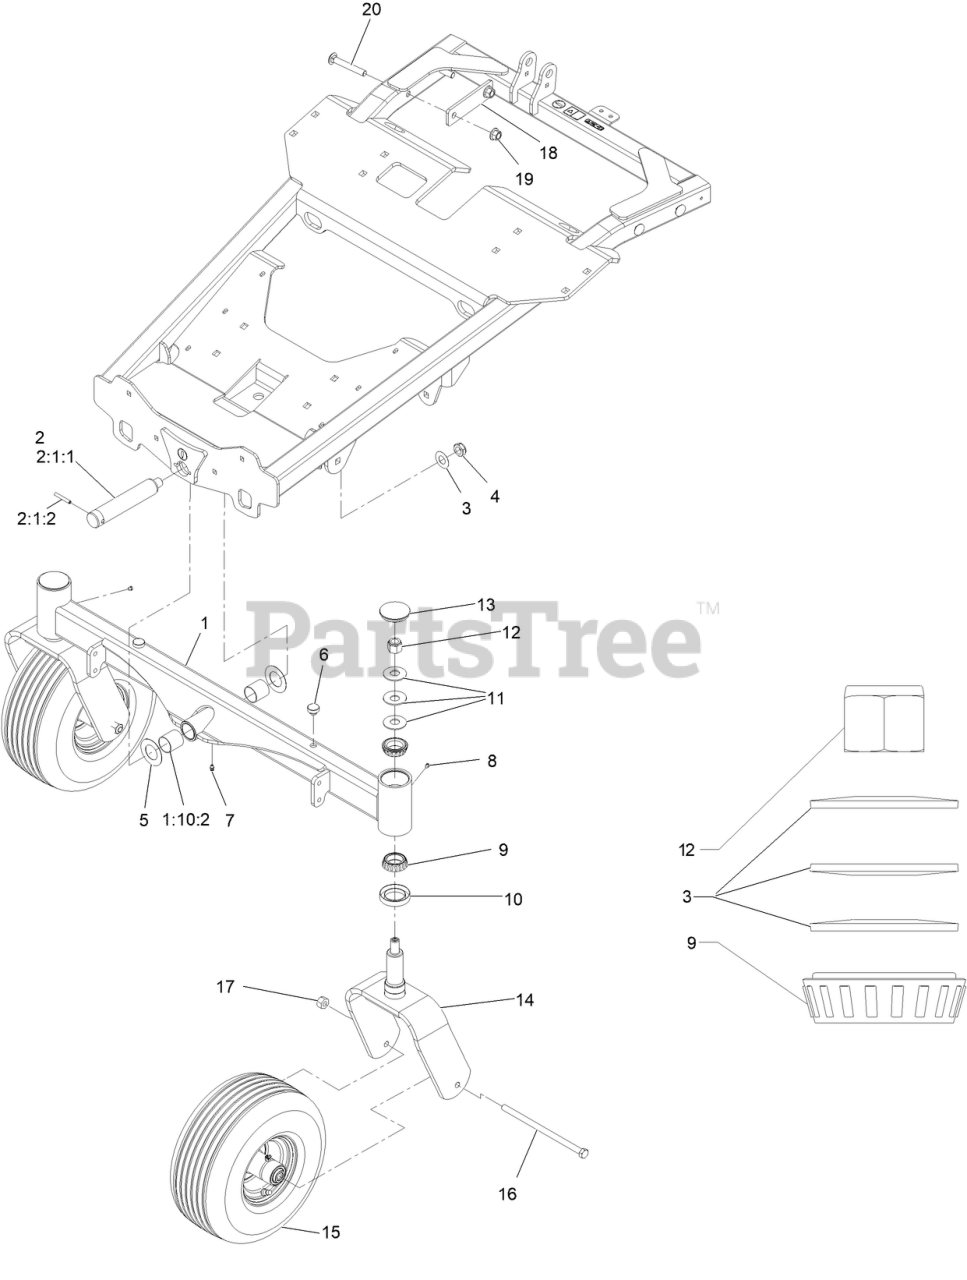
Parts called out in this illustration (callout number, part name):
1	Machined Axle ASM W/Bushings
1:10:2	BUSHING-AXLE
2	AXLE PIVOT PIN ASM
2:1:1	PIN-AXLE PIVOT
2:1:2	PIN-ROLL
3	WASHER-THRUST
4	NUT-LOCK, NI
5	WASHER-THRUST
6	BUMPER-RUBBER
7	Zerk 1/4-28 Str Thrd Forming
9	CONE-BEARING, TAPERED
11	WASHER-BELLEVILLE
12	NUT-LOCK, NI
13	CAP-GREASE
14	FORK-CASTOR
15	CASTOR WHEEL ASM
16	SCREW-HH
17	NUT-LOCK, NI
18	PLATE-CLAMP
19	Nut-Lock 1/2-13
20	SCREW-CARR
